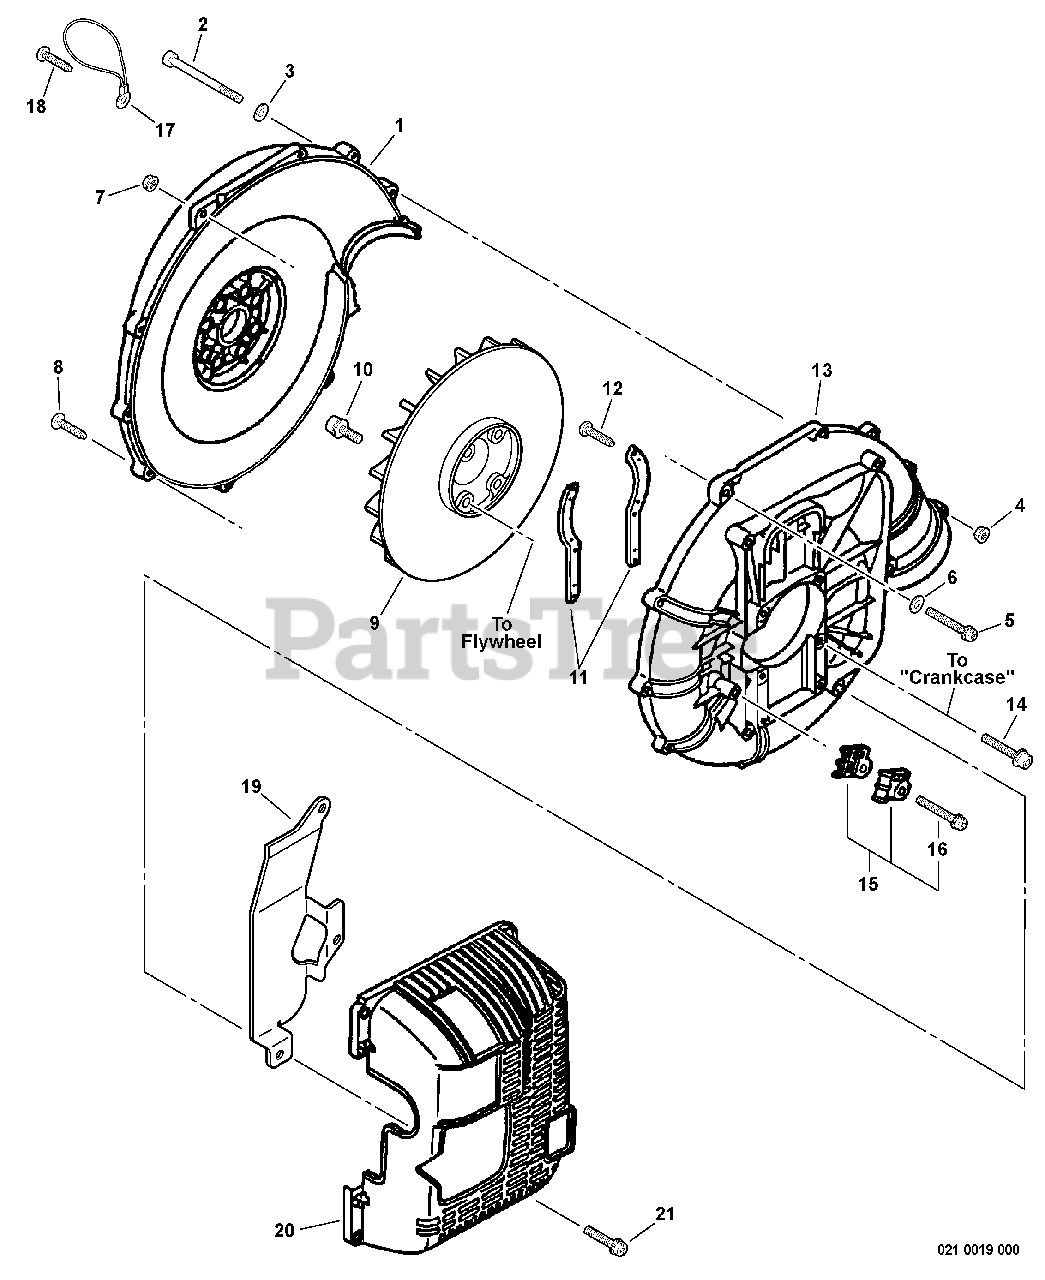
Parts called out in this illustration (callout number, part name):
1	COVER, FAN - INNER -- GRAY
2	SCREW - 5X60
3	WASHER - 5
4	NUT - 5 -- FLANGE
5	SCREW - 5X40
6	WASHER - 5
7	NUT - 5 -- FLANGE
8	SCREW - 5X30
9	FAN
10	SCREW - 5X20
11	BRACKET, ENGINE
12	SCREW - 3X12 -- TAPPING
13	COVER, FAN - OUTER -- GRAY
14	SCREW - 5X32
15	CABLE HOLDER KIT
16	SCREW - 5X25
17	STRAP, SAFETY
18	SCREW - 5X16 -- TAPPING
19	INSULATOR
20	COVER, ENGINE
21	SCREW - 5X18
